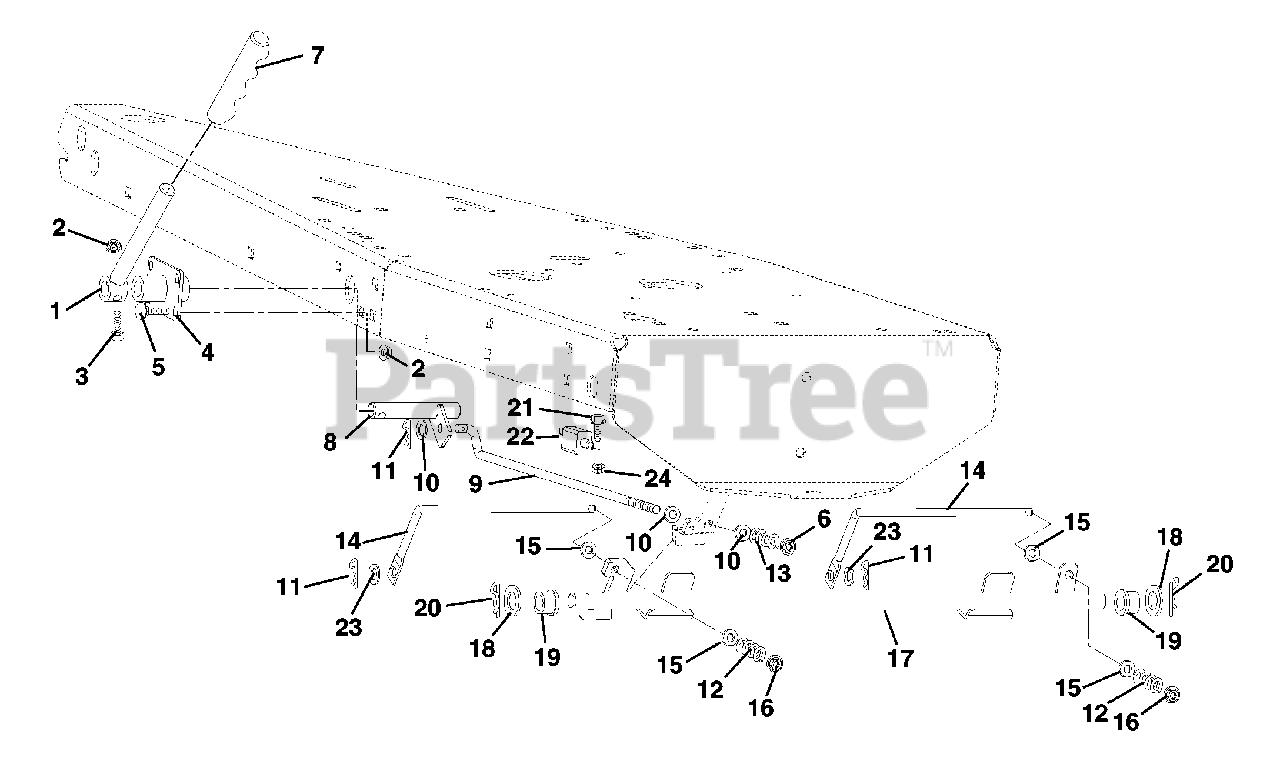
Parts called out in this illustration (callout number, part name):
1	Weldment, Handle
2	Nut, Locking Top Flange .31-18
3	Bolt, Hex .31-18 x 1.50 Grade 5
4	Weldment, Handle Pivot
5	Bolt, Round Head Square Neck .31-18 x .75 Grade 5
6	Nut, Locking Top Flange .38-16
8	Weldment, Pivot Arm
9	Rod, Arm Locking
10	Washer, Flat Steel .406 x .812 x .065
11	Pin, Hair
12	Spring, Compression .045 x .50 x 1.187
13	Spring, Compression .063 x .53 x 1.187
14	Rod, Brake Actuating
15	Washer, Flat Steel .344 x .688 x .065
16	Nut, Locking Top Flange .31-18
17	Shaft, Brake
18	Washer, Flat Steel .875 x 1.50 x .12
19	Bushing, Flange .63 x 1.00 x .625 Nylon
20	Pin, Spring Clip
21	Screw, Tapping 10-24 x .75 Hex Washer Head
22	Switch, Interlock NC
23	Washer, Flat Steel .406 x .812 x .065
24	Nut, Locking-Nylon 10-24 with Insert
